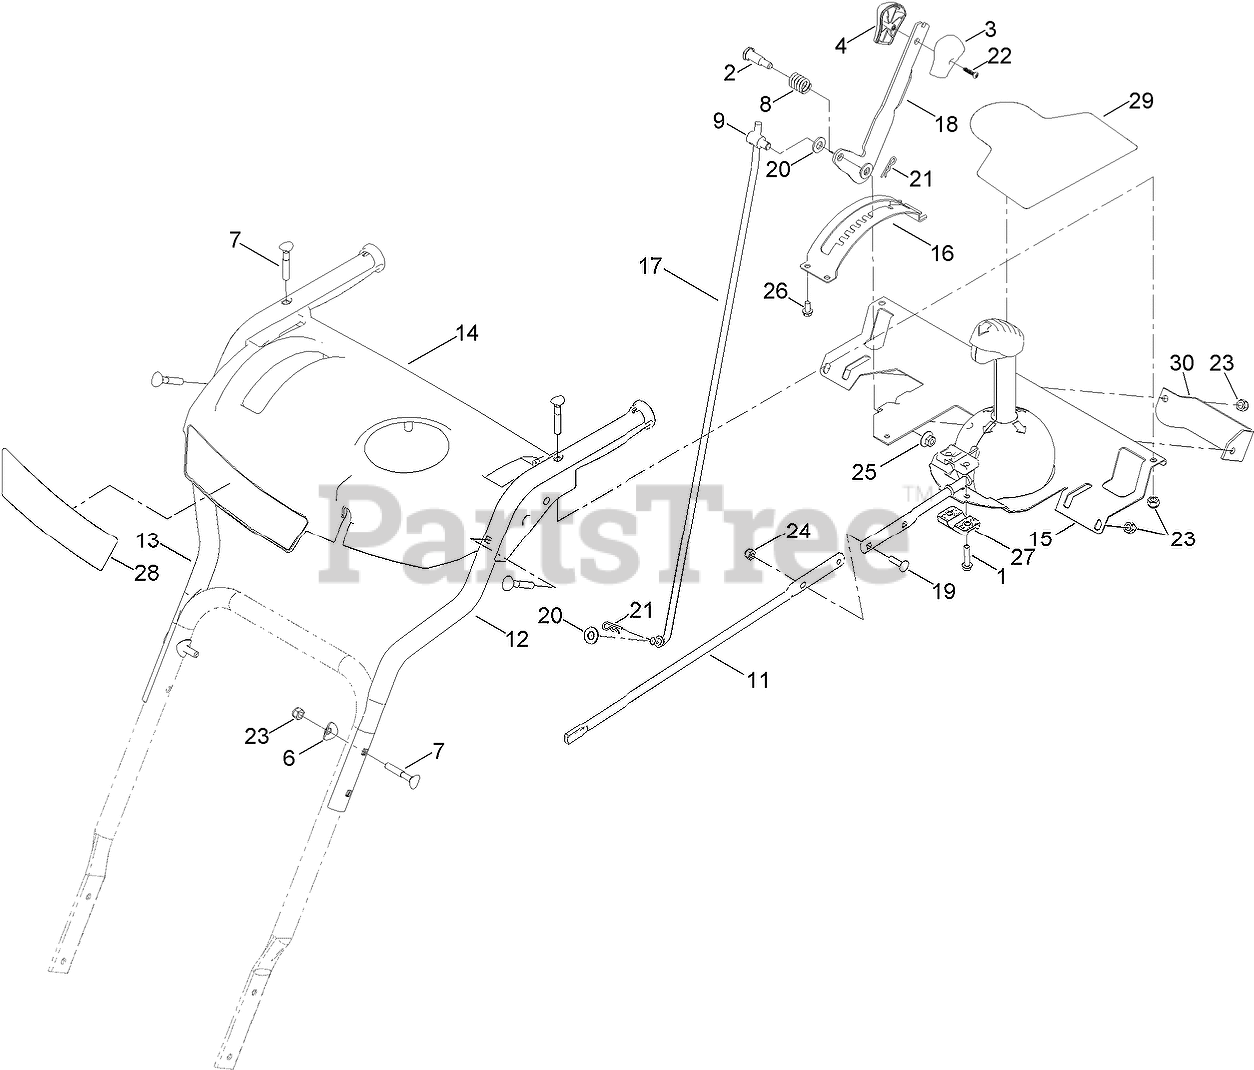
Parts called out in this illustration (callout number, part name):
1	SCREW-PLASTITE
2	SCREW-SHOULDER
3	KNOB-SHIFT, LH
4	KNOB-SHIFT, RH
6	WASHER
7	SCREW-HANDLE
8	SPRING-COMPRESSION
9	TRUNNION-ROD
11	ROD-CHUTE, FRONT
12	HANDLE-UPPER, LH
13	HANDLE-UPPER, RH
14	PANEL-CONTROL, MASTER
15	SUPPORT-PANEL, CONTROL
16	MOUNT-SELECTOR, SPEED
17	ROD-SELECTOR, GEAR
18	SELECTOR-SPEED
19	SCREW-CARR
20	WASHER-FLAT
21	PIN-COTTER
22	SCREW-PPH
23	NUT-LOCK, NI
24	NUT-LOCK, NI
25	NUT-HF
26	SCREW-PLASTITE
27	SUPPORT-ROD
28	DECAL-MODEL
29	TAG-HANG, CHUTE CONTROL
30	PLATE-SUPPORT, SHIFT
